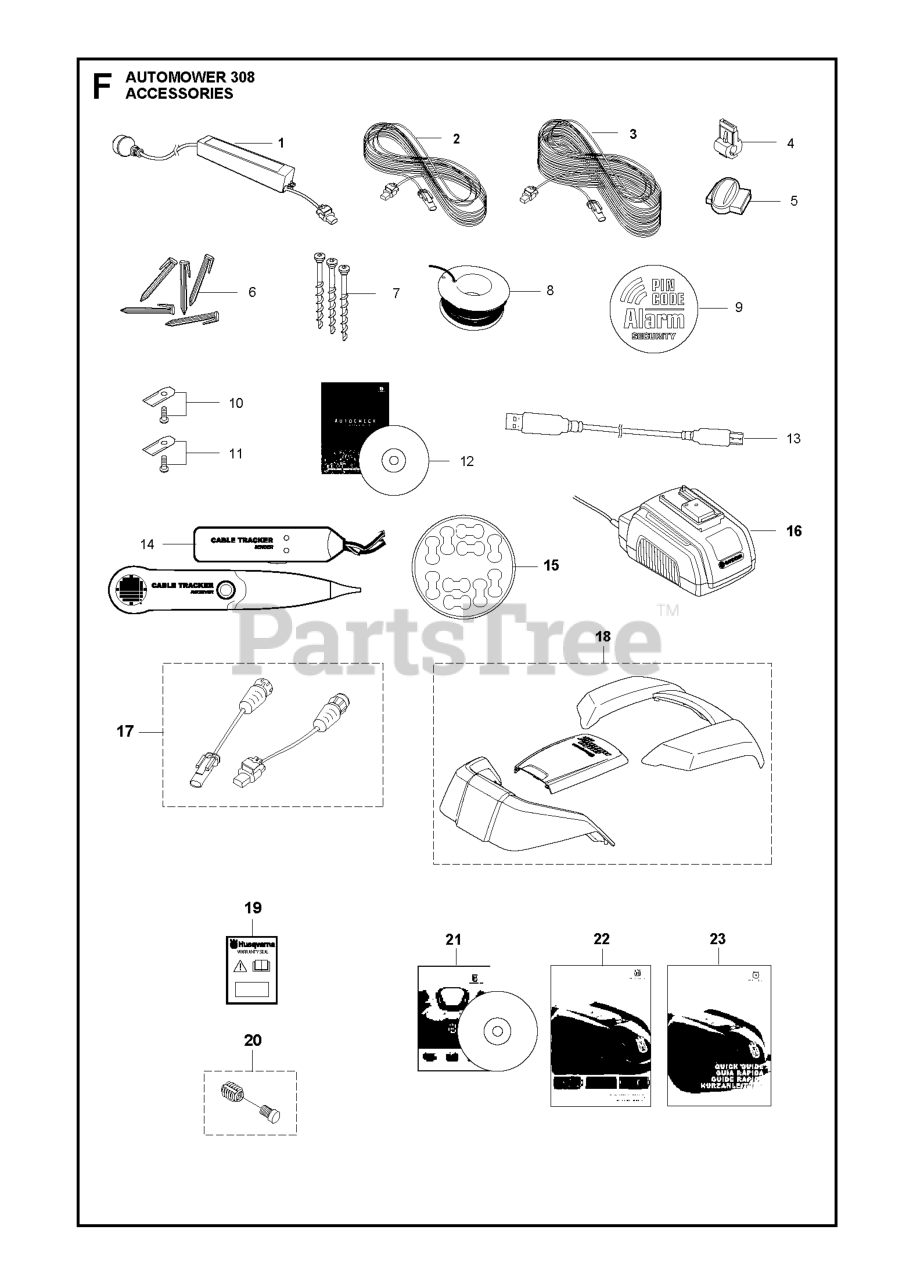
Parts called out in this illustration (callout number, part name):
4	CONNECTOR 5 PCS, BLISTER
4	BRAKER
5	SPLICE KIT
5	COUPLER SPLICER, 100 PCS
5	COUPLER SPLICER, 5 PCS,
6	STAPLE 100 PCS
6	STAPLE 100 PCS, BLISTER
7	SCREW KIT KIT INCLUDES THREE S
7	SCREW 3 PCS, BLISTER PACK
8	LOOP WIRE 150M
8	WIRE 150M, BLISTER
8	WIRE 250M
9	LABEL SECURITY
10	BLADE - BULK PACK 500 PCS
10	BLADE KIT
10	BLADE - 30 PCS
10	BLADE
11	BLADE 300PCS -SINGLE HOLE THIC
11	BLADE CARBON STEEL, THICK BLAD
11	BLADE BLADE KIT INCL PACKAGING
11	BLADE 9PCS EXTRA THICK
14	TEST EQUIPMENT
15	STICKER CABLE MARKERS KIT 10PC
19	LABEL WARRANTY SEAL KIT 10 PK
19	LABEL WARRANTY SEAL DEALER
20	THREAD INSERT KIT: THREAD INSE
